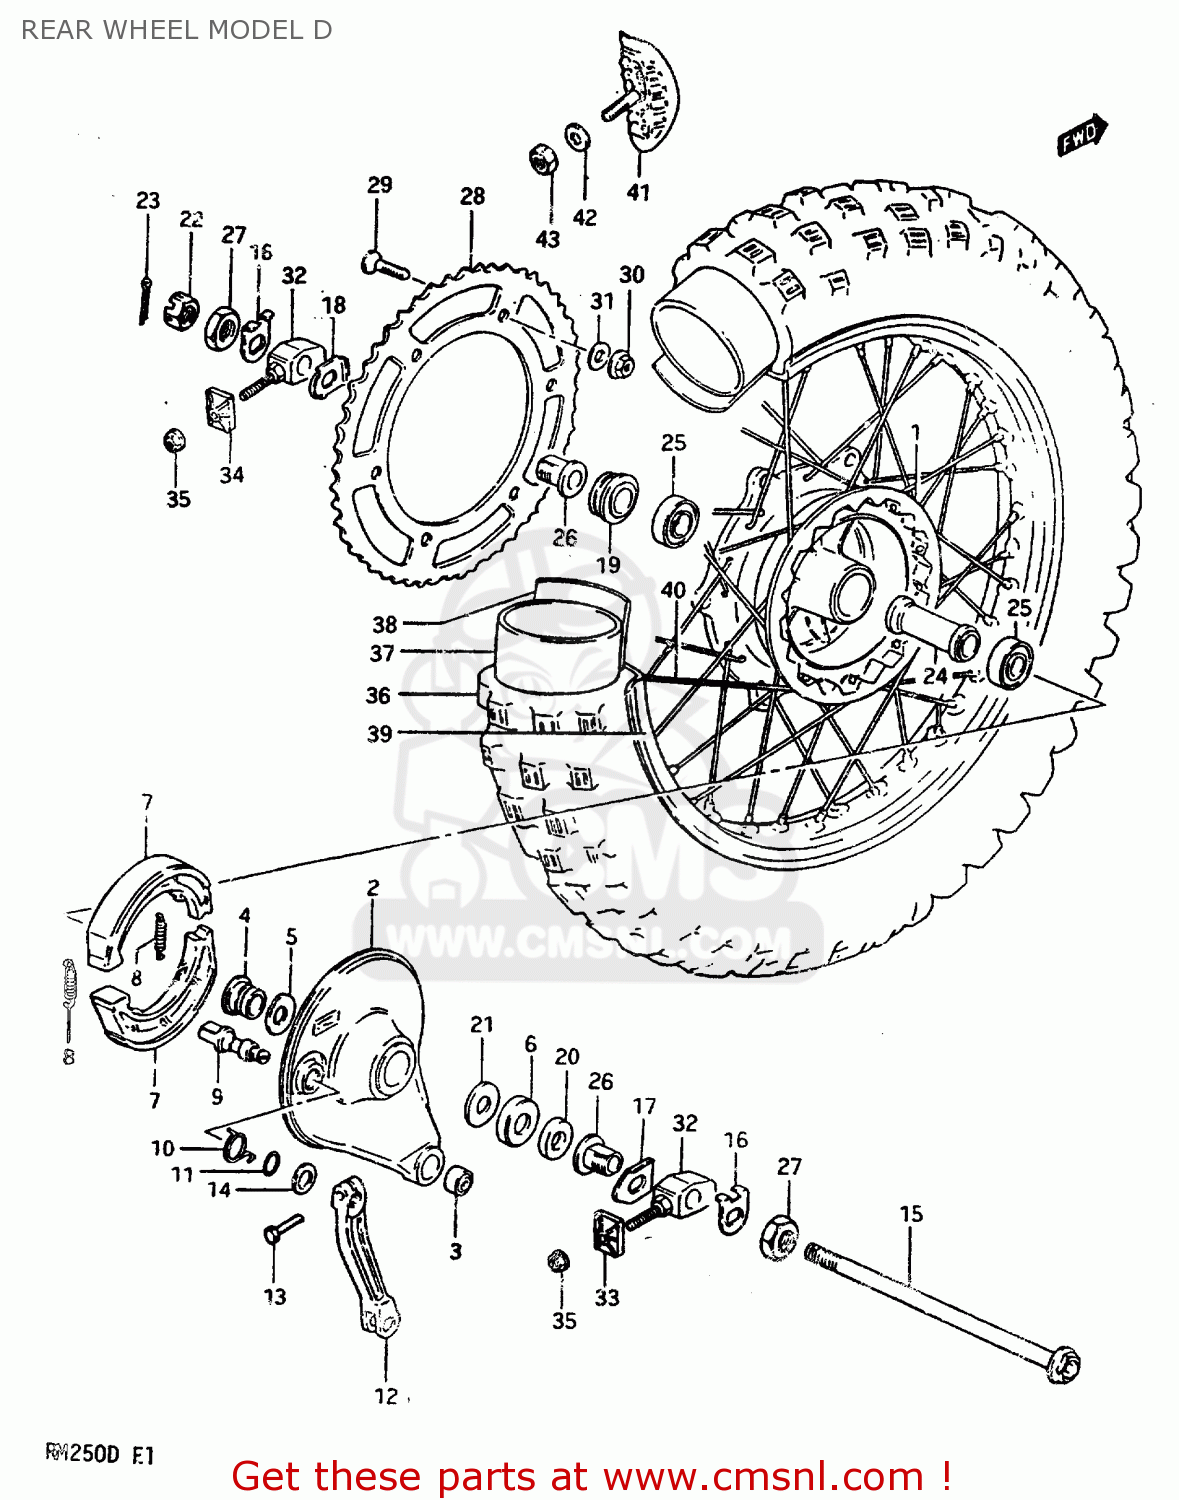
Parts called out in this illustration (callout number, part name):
1	HUB,REAR WHEEL
2	PANEL SET,REAR
3	SPHERICAL BRNG,TORQUE LINK
4	SPACER,RR BRAKE ANCHOR PANEL
5	SEAL,OIL(20X27X5)
6	CVR,RR BRAKE AHR PNL DUST SEAL
7	SHOE,BRAKE (MCA)
8	SPRING(L:35.8)
9	CAM,FR BRAKE
10	SPRING
11	O RING(D:2.5,ID:11.4)
12	LEVER,RR BRAKE CAM
13	BOLT
14	WASHER(12.5X20X1)
15	AXLE,REAR
16	WASHER,CHAIN ADJUSTER GUIDE
17	PLATE,CHAIN ADJUSTER,RIGHT
18	PLATE,CHAIN ADJUSTER,LEFT
19	SPACER,RR AXLE,L
20	SPACER,REAR AXLE,RIGHT
21	WASHER,THRUST
22	NUT
23	COTTER PIN
24	SPACER
25	BEARING
26	SPACER,CHAIN ADJUSTER
27	NUT
28	SPROCKET,REAR
29	SCREW(8X33.5)
30	NUT
31	WASHER
32	ADJUSTER,CHAIN
33	PLATE,CHAIN ADJUSTER GEAR
34	PLATE,CHAIN ADJUSTER GEAR
35	NUT
36	TIRE
37	TUBE,INNER
38	PROTECTOR,WHEEL,INNER
39	RIM,REAR WHEEL (2.15-18)(
40	SPOKE SET,REAR
41	STOPPER,BEAD
42	WASHER
43	NUT
